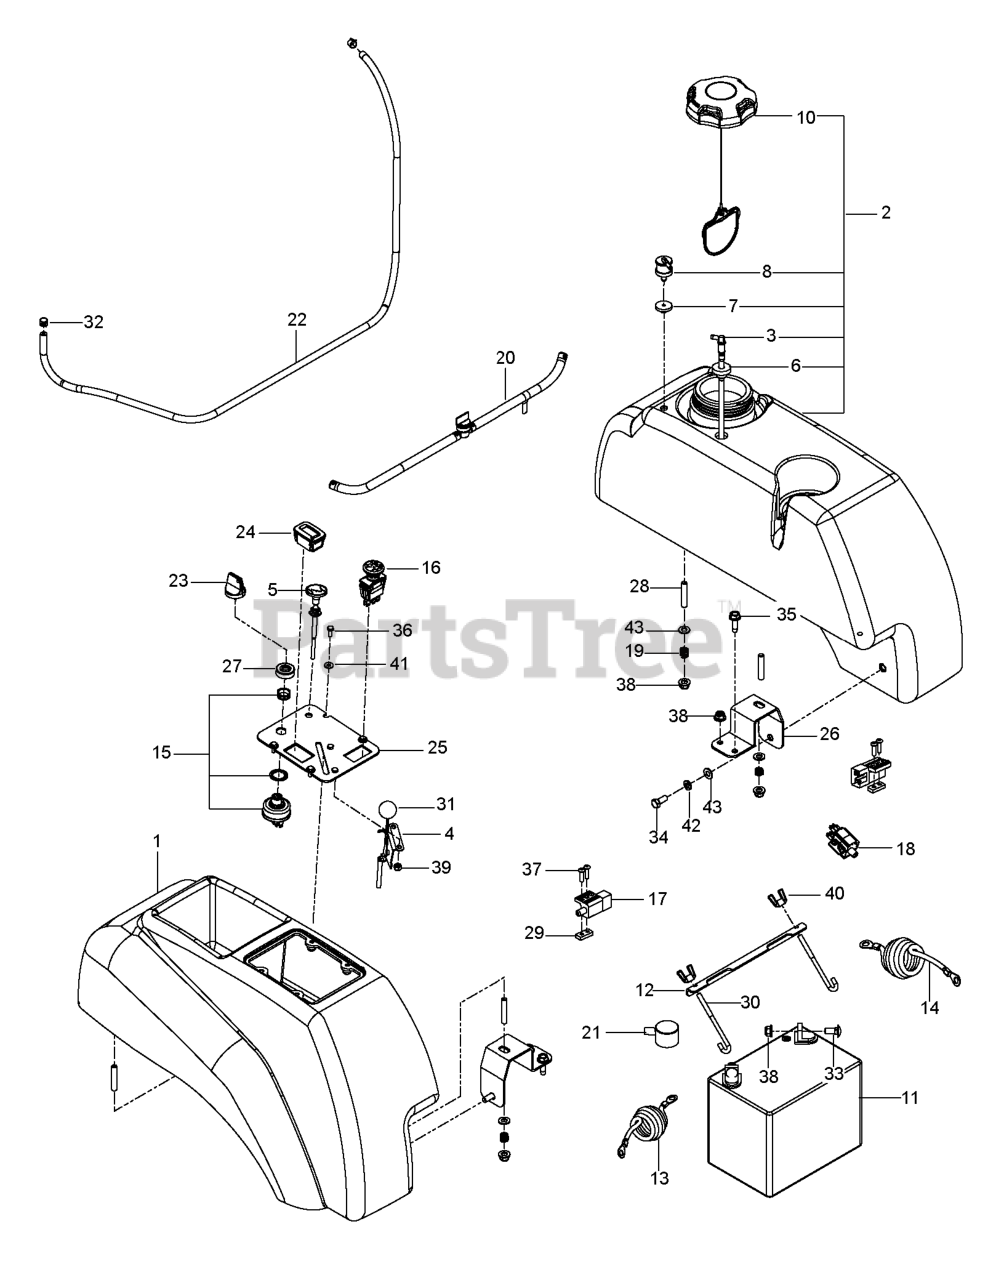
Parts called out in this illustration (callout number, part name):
1	FENDER CONSOLE
2	FUEL.TANK.ASSY.LH.MZ.GRY
3	FITTING, FUEL
4	THROTTLE CABLE
5	CHOKE CABLE
6	RUBBER GROMMET
7	GROMMET, CHECK VALVE
8	VALVE.FUEL.CHECK
10	CAP, FUEL
11	BATTERY, 12 V 330 AMP
12	BRACKET, BATTERY MOUNT
13	CABLE.BATT.SOLENOID.MZ.RED.25"
14	CABLE.GROUND.BATT.MZ.BLACK.39"
15	SWITCH, IGNITION, INDAK
16	RP SWITCH.PTO.TERMINAL.STD.RED
17	SWITCH INTERLOCKT
18	SWITCH.INTRLCK.CLUTCH.
20	FUEL.HOSE.SHUT.OFF.ASM.10".10"
21	COVER.TERMINAL.BATTERY
22	HOSE.3/16"VAPOR.27"
23	KEY, IGNITION
24	GUAGE.SRVCMNDR.HRMTR.
25	PLATE, CONSOLE, BLK
26	SUPPORT, TANK, BLK
27	CAP IGNITION NUT
28	STUD, 5/16C
29	PLATE NUT ZTR
30	HOOK, "J"
31	KNOB.ROUND.BALL.BLACK
32	CLAMP, HOSE
33	RP BOLT 5/16-18 X3/4 ZN/YEL GR
34	BOLT.FIN.HEX.5/16-18X3/4
35	SCREW
36	HCS #10-24 X 1/2
37	SCR #10-24 X .75 SKT HD BLK
38	5/16-18 NYLOC FLANGE NUT
39	NUT 10-24 NYLOC
40	WING NUT 1/4
42	WASH.5/16.SLW.ZD
43	WASHER
